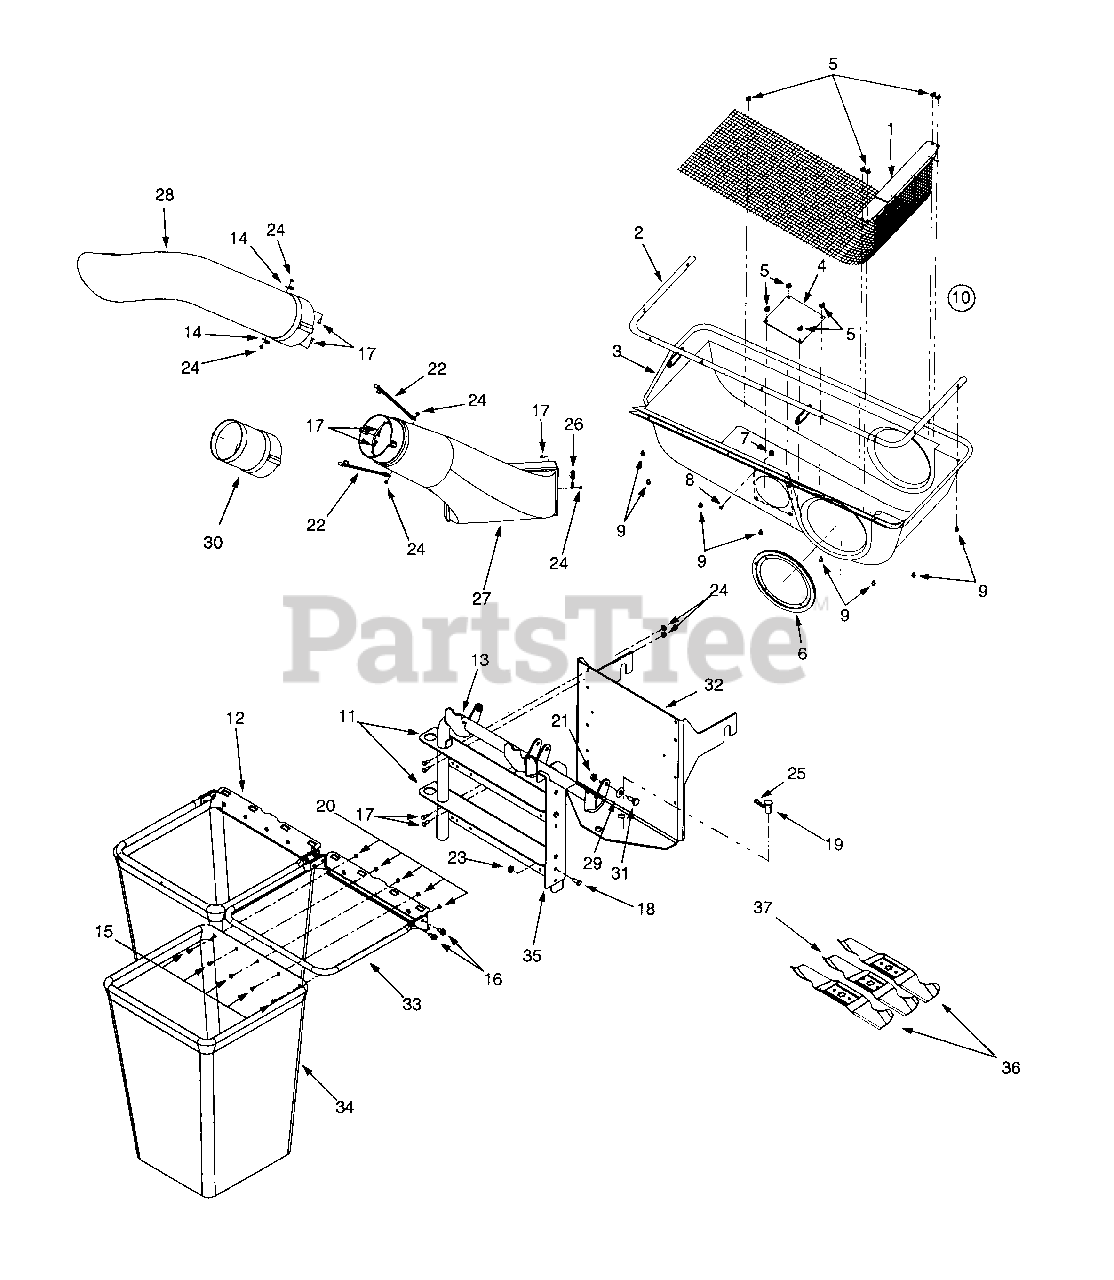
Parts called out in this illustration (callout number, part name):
3	Grass Catcher Cover
4	Plastic Plate, 1/8 x 5.6 sq.
5	Zip Twist Fastener
6	Tube Seal
7	U-Type Speed Nut, #10-24
8	Screw, #10-24 x .5
9	Hex Screw, 1/4-20 x.5
10	Cover Assembly
14	Retainer Hook Bracket
15	Screw, #10-24 x .5
16	Self Tapping Screw, 5/16-18 x .625
17	Hex Cap Screw, 1/4-20 x .62
18	Hex Cap Screw, 5/16-18 x .75
20	Hex Sems Nut, 10-24
21	Hex Flange Lock Nut, 3/8-16
22	Retainer Strap Assembly
23	Hex Flange Lock Nut, 5/16-18
24	Hex Flange Lock Nut, 1/4-20
25	Internal Cotter Pin, .148 x 3
26	Retainer Strap Assembly
27	Discharge Chute
28	Chute Tube
30	Extension Tube
31	Shoulder Screw, .50 x .27, 3/8-16
34	Bag
36	Star Center Blade, 16.28
37	Star Center Blade, 14.88
